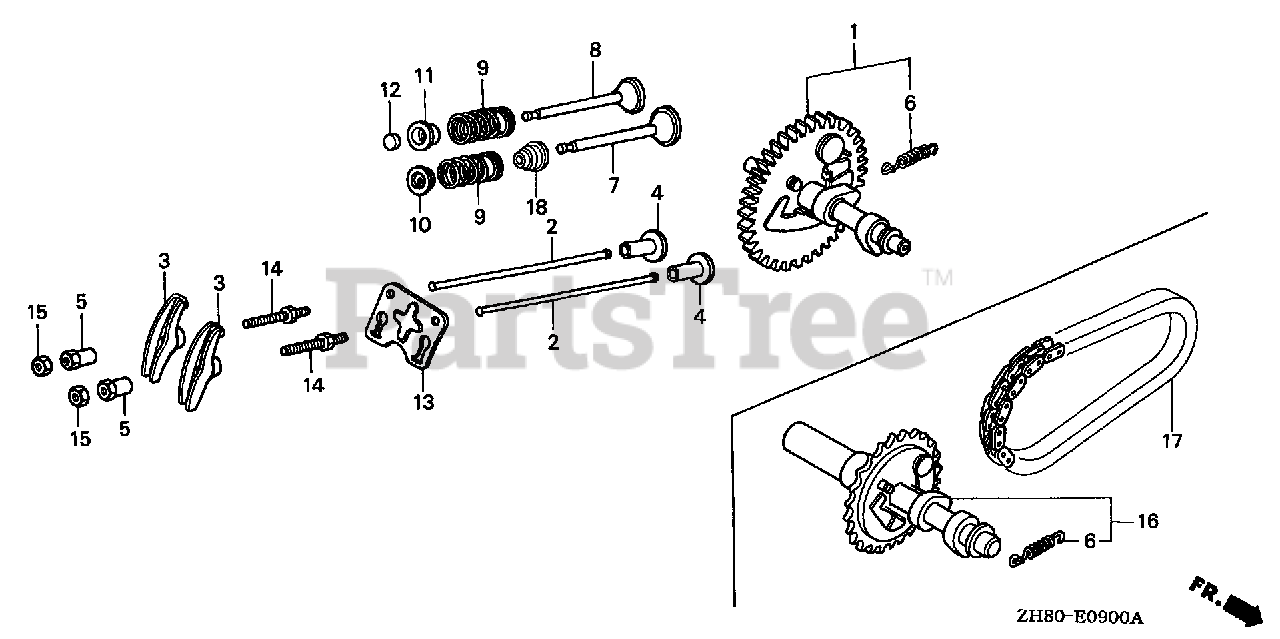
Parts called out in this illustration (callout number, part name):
1	CAMSHAFT ASSY.
2	ROD, PUSH
3	ARM, VALVE ROCKER
4	LIFTER, VALVE
5	PIVOT, ROCKER ARM
6	SPRING, WEIGHT RETURN
7	VALVE, IN.
8	VALVE, EX.
9	SPRING, VALVE
10	RETAINER, IN. VALVE SPRING
11	RETAINER, EX. VALVE SPRING
12	ROTATOR, VALVE
13	PLATE, PUSH ROD GUIDE
14	BOLT, PIVOT (8MM)
15	NUT, PIVOT ADJUSTING
18	SEAL, VALVE STEM
